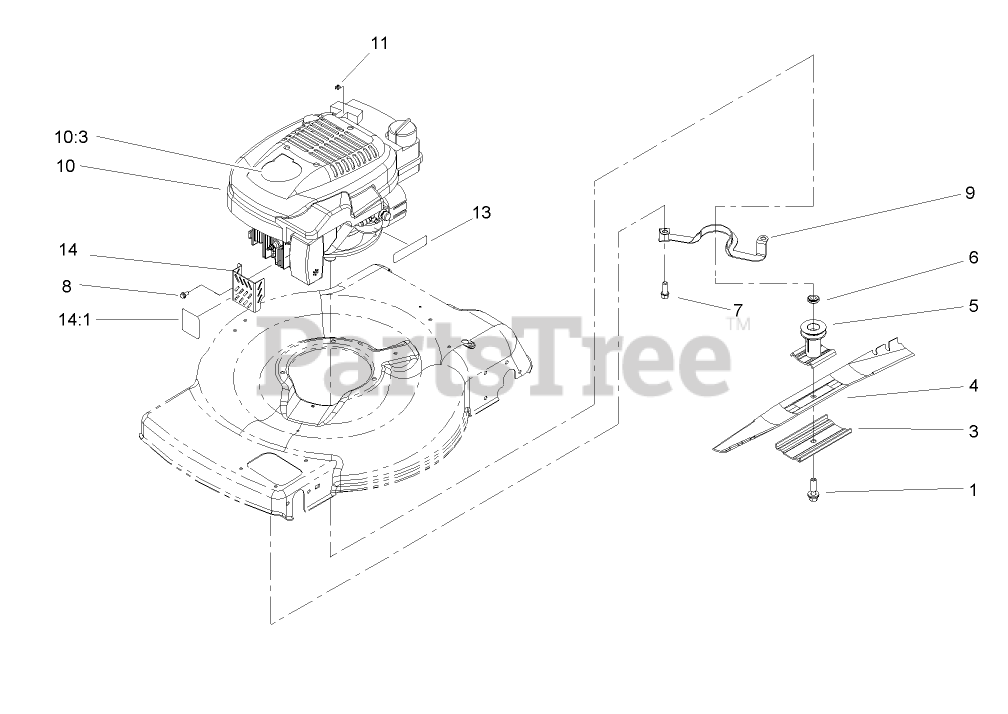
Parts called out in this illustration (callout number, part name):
5	DRIVER-BLADE
6	SPACER-DRIVER
7	SCREW-TAPTITE
8	SCREW-HWH
9	GUIDE-BELT
10	Loose Parts Package
10:3	DECAL-RECOIL
11	STOP-ROPE
13	DECAL-PRIMER
14	MUFFLER GUARD ASM
14:1	DECAL-WARNING
